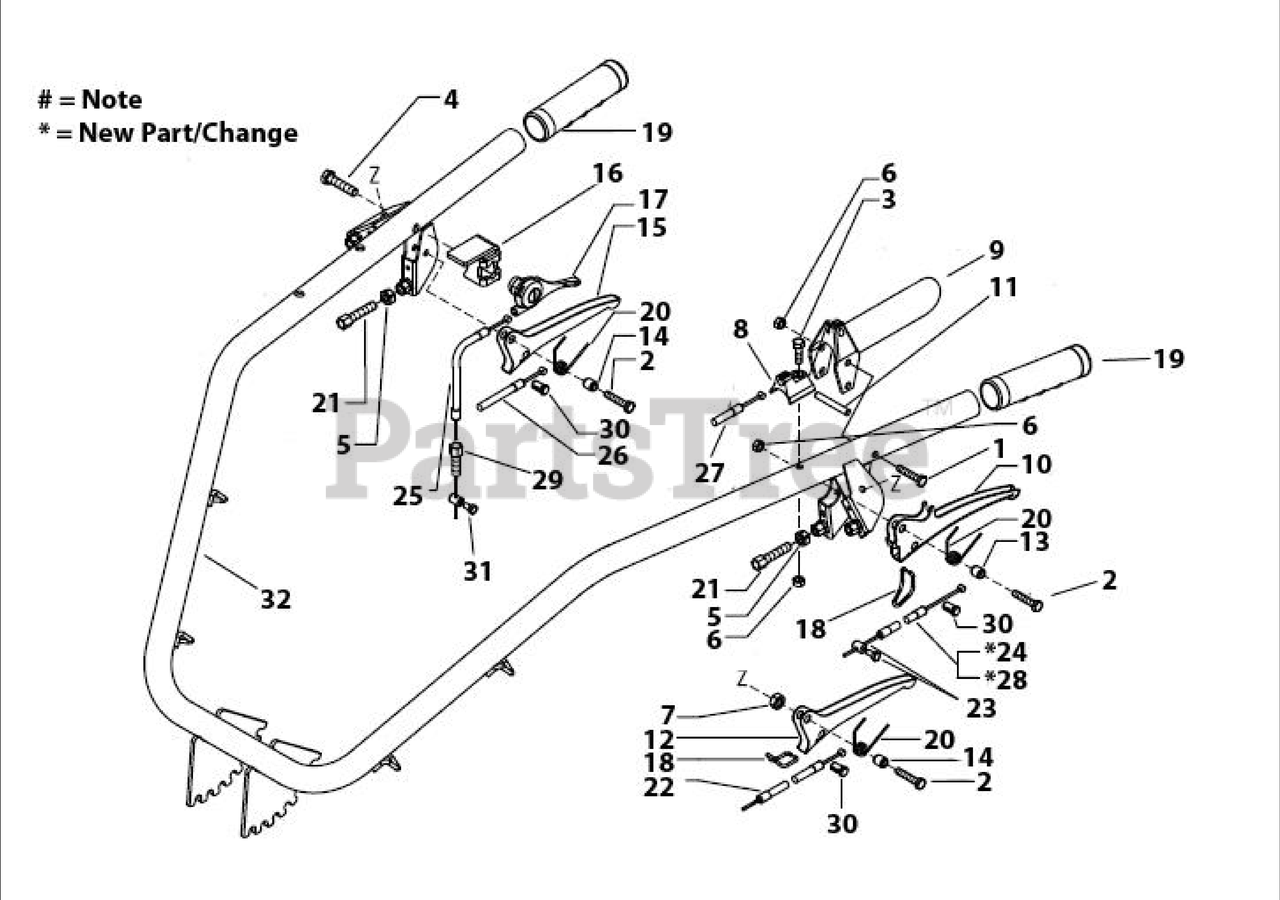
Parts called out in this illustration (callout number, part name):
1	CAP SCREW, M6X45
2	CAP SCREW, M6X25
3	CAP SCREW, M6X35
4	SCREW
5	NUT, M8
6	NUT, SELF LOCK M6
7	NUT, SELF LOCKING M8
8	CABLE GUIDE
9	LEVER, MOTOR STOP (OPC)
10	LEVER, CLUTCH
11	PIN, MOTOR STOP LEVER
12	LEVER, BRAKE (LEFT OR RIGHT)
13	SPACER, LEVER
14	SPACER, LEVER
15	LEVER, STEERING RELEASE
16	PANEL
17	LEVER, THROTTLE
18	CLIP, WIRE STOP
19	GRIP (LEFT OR RIGHT)
20	SPRING, LEVER
21	SCREW, ADJUSTING M8
22	CABLE & SHEATH BRAKE (L OR R)
23	CLAMP, CABLE
24	CLUTCH CABLE (ELECTRIC START)
25	CABLE, THROTTLE
26	CABLE, STEERING RELEASE
27	CABLE, LEVER MOTOR STOP (OPC)
28	CLUTCH CABLE (RECOIL START)
29	SCREW, ADJUSTING M6
30	BARREL
31	CLAMP, THROTTLE
32	HANDLEBAR
